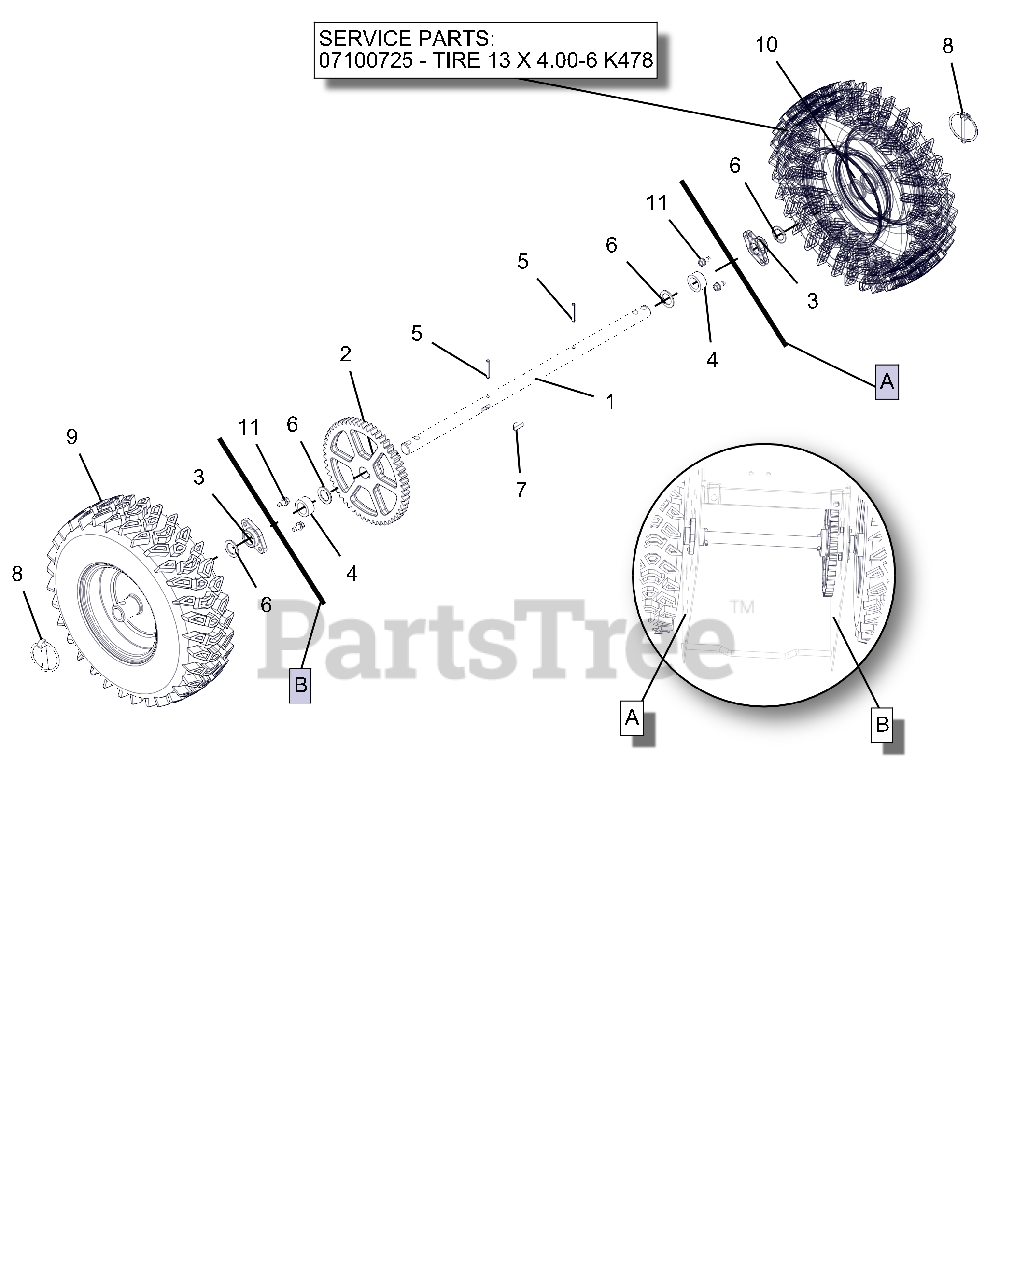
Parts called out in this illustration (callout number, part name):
1	SHAFT, AXLE
2	SPUR GEAR, 54T .75ID X 6.75PD
3	BSHG .75X1.125X.65
4	BSHG-SLV .766 X 1.125 X .500
5	PIN-ROLL .188X1.25
6	WSHR-FL-STL.754X1.125X.062YWZC
7	KEY-WDRF .25X.750X.313 SAE91
8	PIN-LOK .31X1.75
9	TIRE/WHEEL, RH 4.10-6 PIN K478
10	TIRE/WHEEL, LH 4.10-6 PIN K478
10	TIRE, 4.10-6 K478
11	SCR-TAP .25-20X.50 HWH TR YWZ
